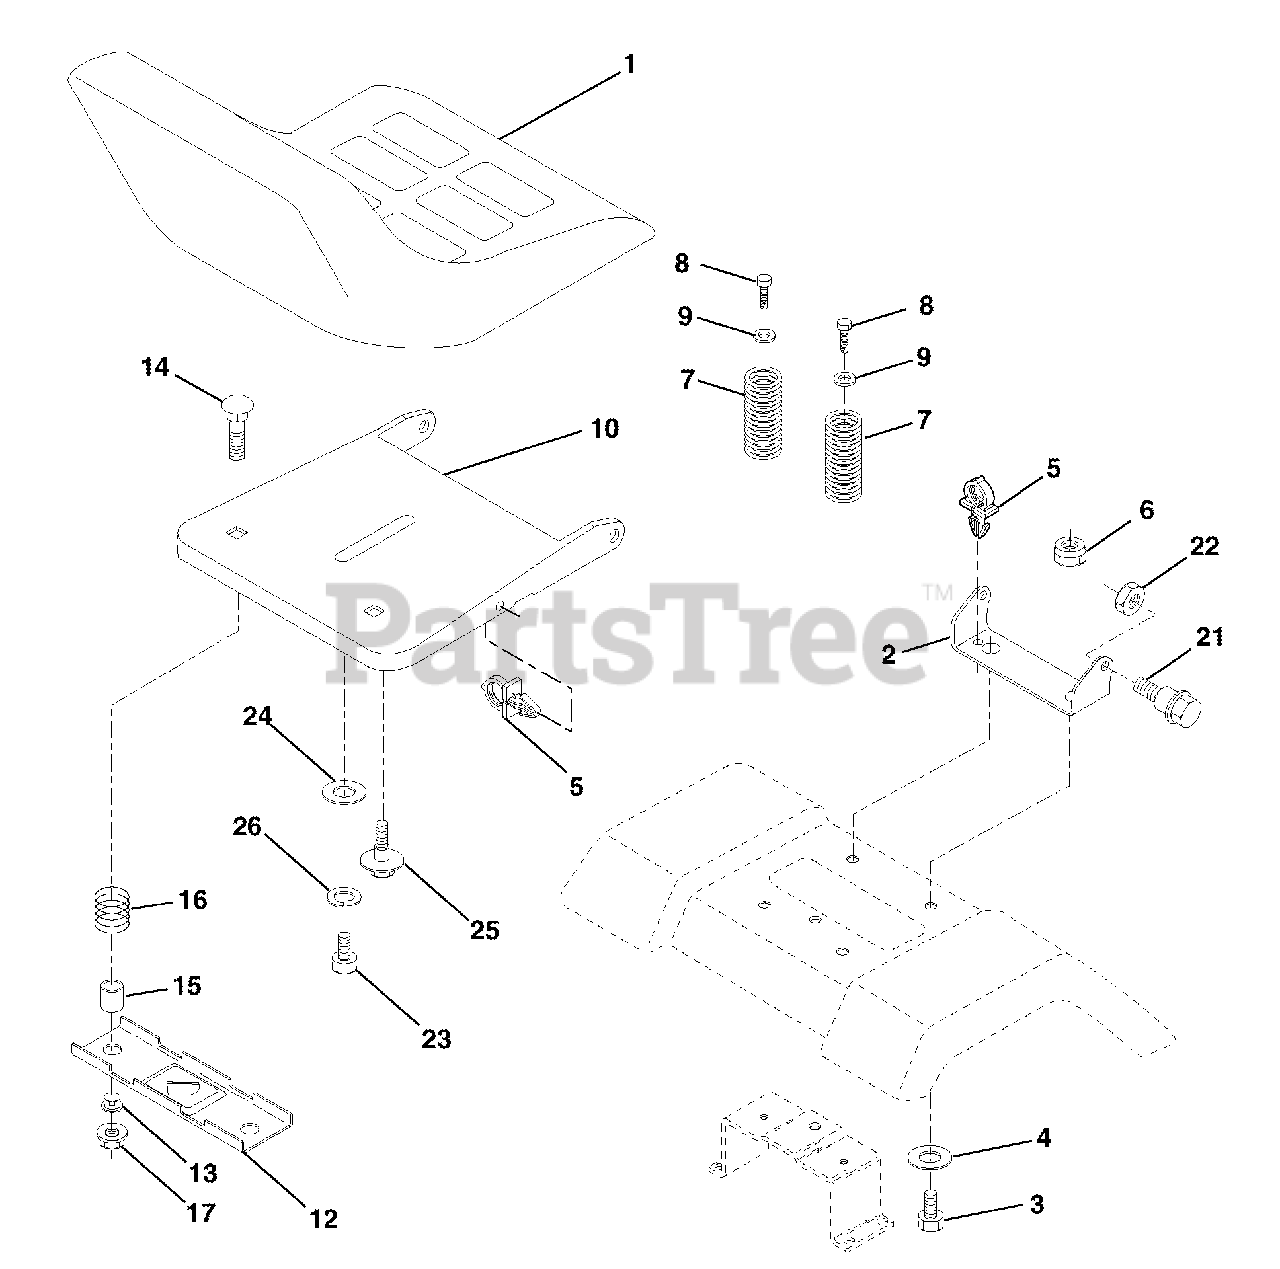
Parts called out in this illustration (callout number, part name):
1	Seat
2	Bracket Pnt Pivot Seat (blk)
3	Bolt
4	Washer 13/32 x 1 x 10 Ga
5	Clip Push-In Hinged
6	Nut
7	Spring Seat Cprsn 2 250 Blk Zi
8	Screw 3/8-16 x 1.5
9	Washer 13/32 x 1 x 14 Ga
10	Pan Pnt Seat (blk )
12	Bracket Pnt Mounting Switch
13	Bushing Snap Blk Nyl 50 Id
14	Bolt Rdhd Sht Nk 1/4-20 x 1-1/2
15	Spacer Split 28 x 96 Yel Zinc
16	Spring Cprsn 1 27 Blk Pnt
17	Nut Lock 1/4 Lge Flg Gr 5 Zinc
21	Bolt Shoulder 5/16-18 Unc Blkz-2A
22	Nut
23	Bolt Hex Black
24	Washer 17/32 x 1-3/16 x 12 Ga
25	Bolt Shoulder 5/16-18 x 62
26	Lockwasher
